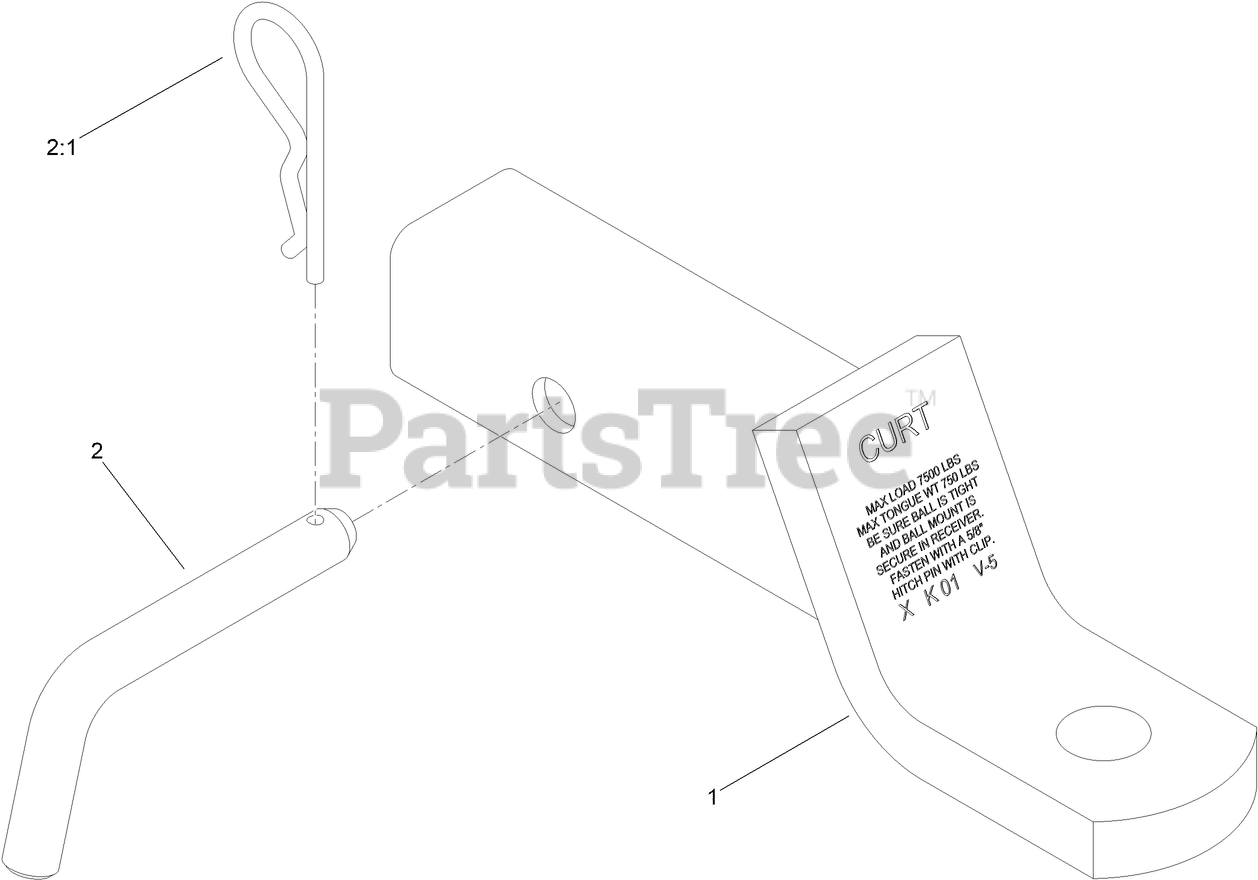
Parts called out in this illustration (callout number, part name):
1	HITCH-BALL MOUNT, CLASS 3
2	PIN-HITCH ASM
2:1	PIN-HAIR
